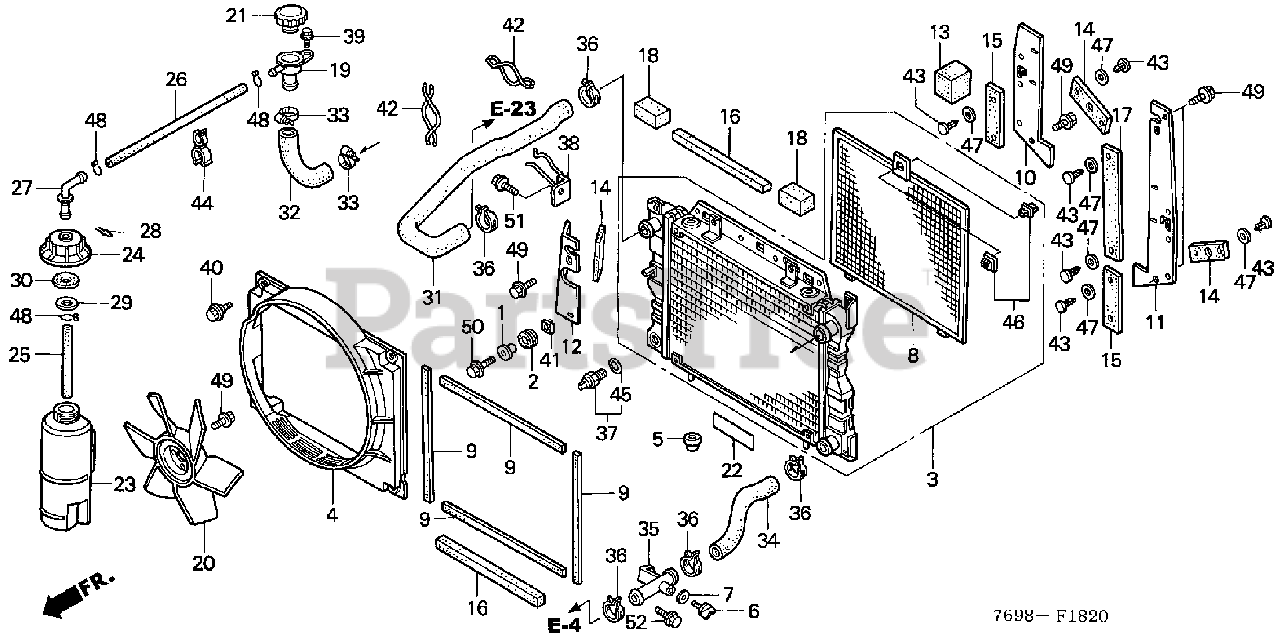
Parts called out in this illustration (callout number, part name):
1	COLLAR, DUST COVER
2	GROMMET, OIL COOLER
3	RADIATOR ASSY.
4	SHROUD ASSY.
5	COLLAR (7.9X20X13)
6	VALVE, DRAIN (TOYO)
7	GASKET, DRAIN (TOYO)
8	SCREEN, FR.
9	SEAL, SHROUD
10	PLATE, R. COOLING SEAL
11	PLATE, L. COOLING SEAL
12	PLATE B, R. COOLING SEAL
13	SEAL A, RADIATOR (50MM)
14	SEAL B, RADIATOR (125MM)
15	SEAL C, RADIATOR (110MM)
16	SEAL D, RADIATOR (285MM)
17	SEAL E, RADIATOR (190MM)
18	SEAL F, RADIATOR (35MM)
19	FILLER, NECK
20	FAN, COOLING
21	CAP, RADIATOR
22	SEAL, RADIATOR (120MM)
23	TANK, RESERVE
24	CAP, RESERVE TANK
25	HOSE, RESERVE TANK
26	TUBE, RESERVE TANK (455MM)
27	JOINT, RESERVE TANK
28	CLIP, RESERVE TANK JOINT
29	WASHER, RESERVE TANK
30	GASKET, RESERVE TANK
31	HOSE A, WATER (UPPER)
32	HOSE B, WATER (UPPER)
33	CLAMP, WATER HOSE
34	HOSE, WATER (LOWER) (A)
36	CLIP, WATER HOSE
37	SWITCH ASSY., THERMOSTAT
38	CLAMP, WATER HOSE (UPPER)
39	BOLT, FLANGE (5X16)
40	BOLT, BUMPER
41	NUT, SPRING (6MM)
42	CLIP, PURSE LOCK
43	CLIP, TRIM (5MM) *NH1L* (BLACK)
44	CLAMP, RESERVE TANK TUBE
45	O-RING (13.5X1.4)
47	WASHER, PLAIN (6MM)
48	CLIP, TUBE (C11)
49	BOLT, FLANGE (6X12)
50	BOLT, FLANGE (6X20)
51	BOLT, FLANGE (8X16)
52	BOLT, FLANGE (8X20)
